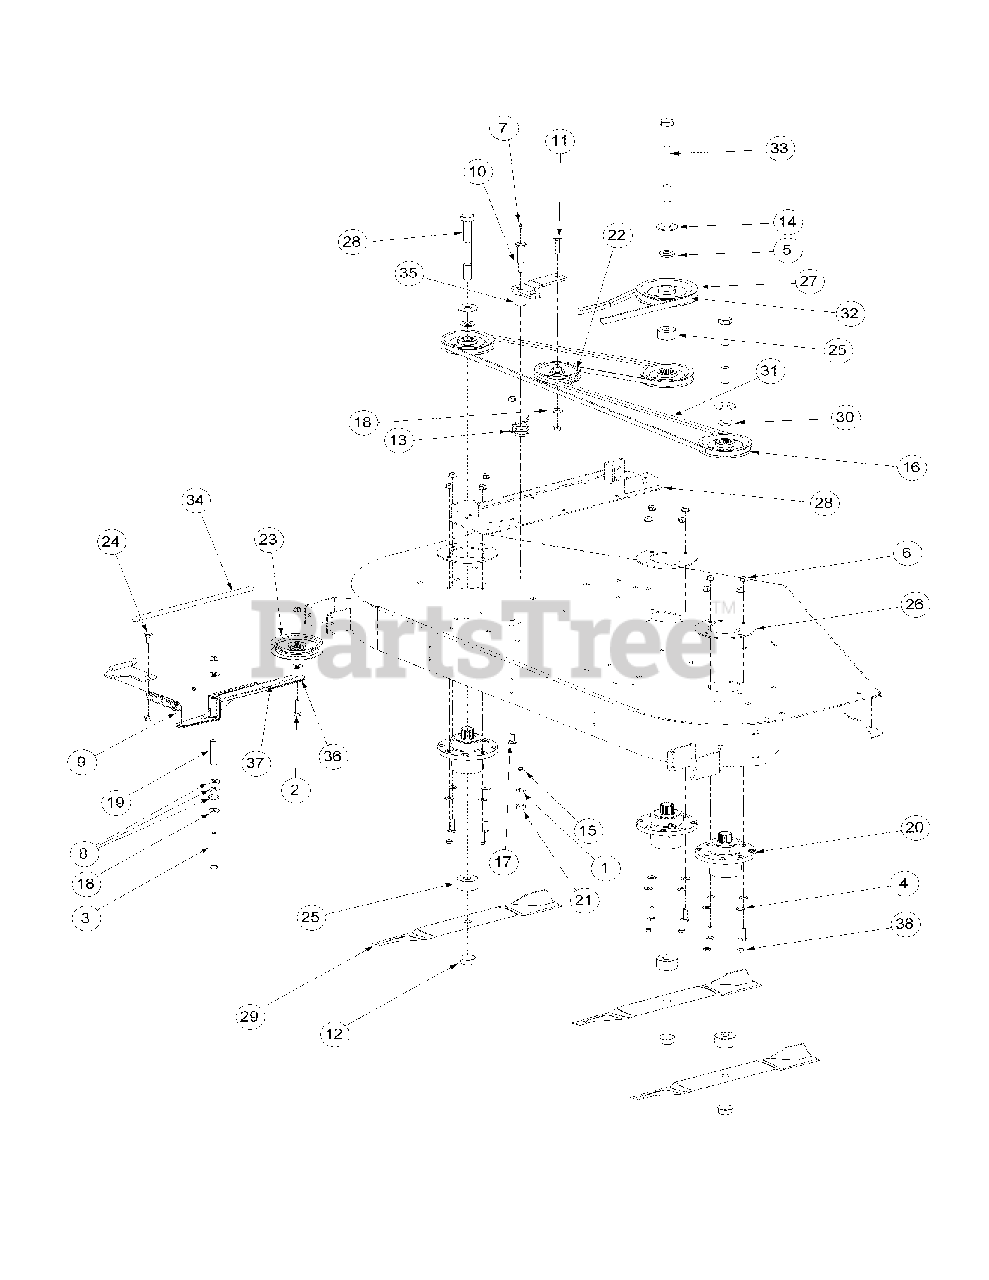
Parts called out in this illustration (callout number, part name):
1	Lock Washer, 7/16
2	Hex Cap Screw, 3/8-16 x 1-1/4
3	Hex Cap Screw, 3/8-16, 4.00
4	Flat Washer, 3/8
5	Caster Spacer
6	Flange Lock Hex Nut, 3/8-16
7	Grease Fitting, 1/4-28 x 3/16
8	Idler Washer
9	Extension Spring, 1.0 x OD x 5.125
10	Shoulder Screw, 7/16-14
11	Hex Carriage Screw, 3/8-16, 1.75
12	Flange Hex Nut, 3/4-16
13	Torsion Idler Spring
14	Flat Washer, .781 ID 2.00 OD, .105
15	Flat Washer, .469 ID, .875 OD, .105
16	V-Pulley, 5.00 OD
17	Carriage Bolt, 3/8-16 x 1
18	Flat Washer, .406 ID, 1.0 OD, .105
19	Spacer, .39 ID x .625 OD x 2.75
20	Aluminum Spindle Assembly
21	Hex Nut, 7/16-14
22	Flat Pulley
23	Idler Pulley, 4.06 OD
24	Shoulder Screw, .50 x .27 Lg., 3/8-16
25	Spacer, .760 ID x 2.00 OD x 1.1
26	Aluminum Spindle Support Plate
27	V-Pulley, 5.774 OD
28	Hex Cap Screw, 3/4-16, 7.00
29	Hi-Lift Blade, 21.0, 0.756 ID
30	Spacer .812 ID x .268 LG
31	V-Belt, A Section x 122.3
32	V-Belt, B Section x 91.2
33	Hex Cap Screw, 3/4-16, 9.00
34	Spring Tension Rod Assembly
35	Idler Arm Assembly, Deck Spindle includes:
36	Idler Arm Assembly, Flat Top Bearing
37	Decal, Idler Location
38	Hex Cap Screw, 3/8-16 x 1-1/2"
